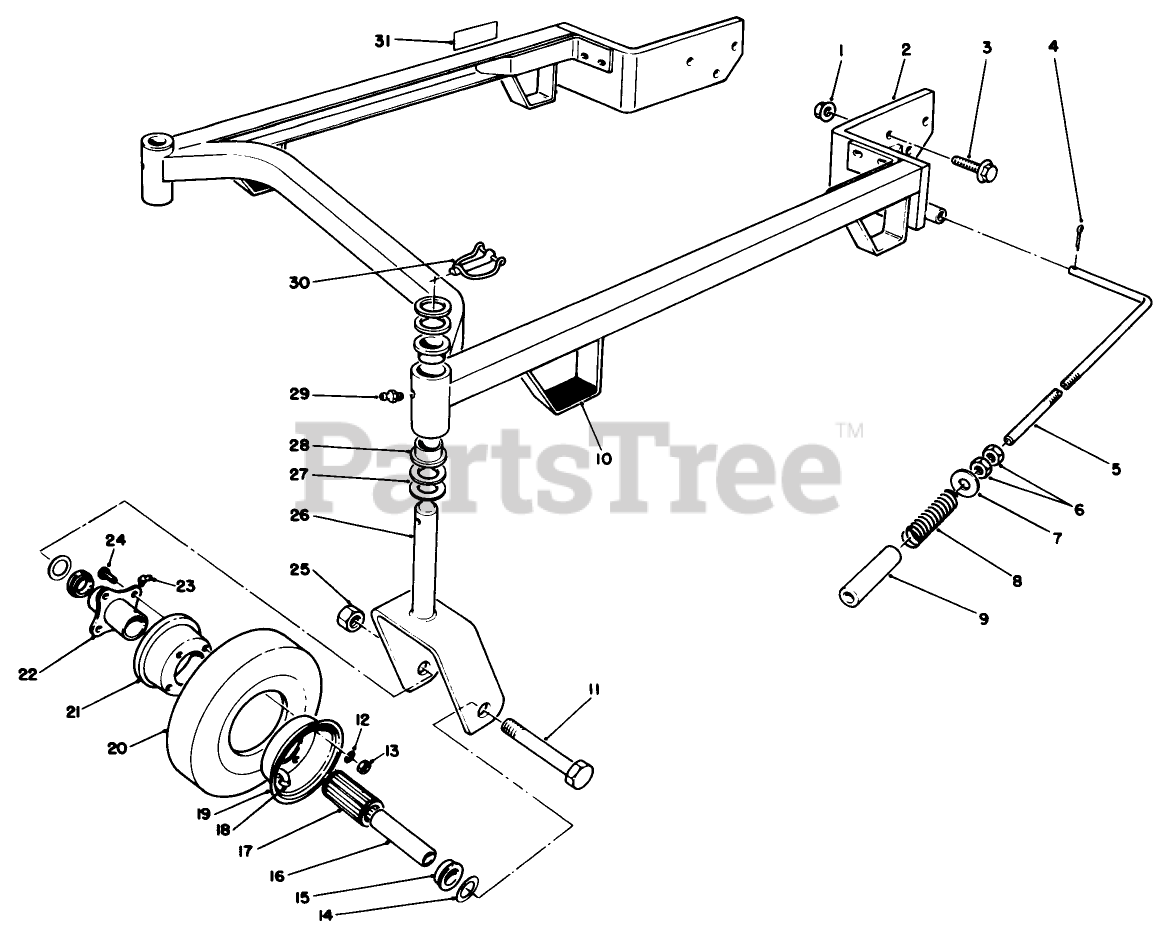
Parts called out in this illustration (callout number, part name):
1	NUT-HF
2	44" SUSPENSION WA
3	SCREW-HHF
4	PIN-COTTER
6	NUT-JAM
7	WASHER
8	SPRING-COMPRESSION
11	SCREW-HH
12	WASHER-LOCK
13	NUT-HEX
14	WHEEL SPACER
15	RETAINER
17	ROLLER BEARING
19	WHEEL HALF-MALE
20	TIRE 8"(4-PLY)
21	WHEEL HALF-FEMALE
22	HUB - CENTERED
23	FITTING-GREASE
24	WHEEL BOLT
25	NUT-LOCK
27	WASHER-THRUST
29	FITTING-GREASE
30	PIN-LYNCH
